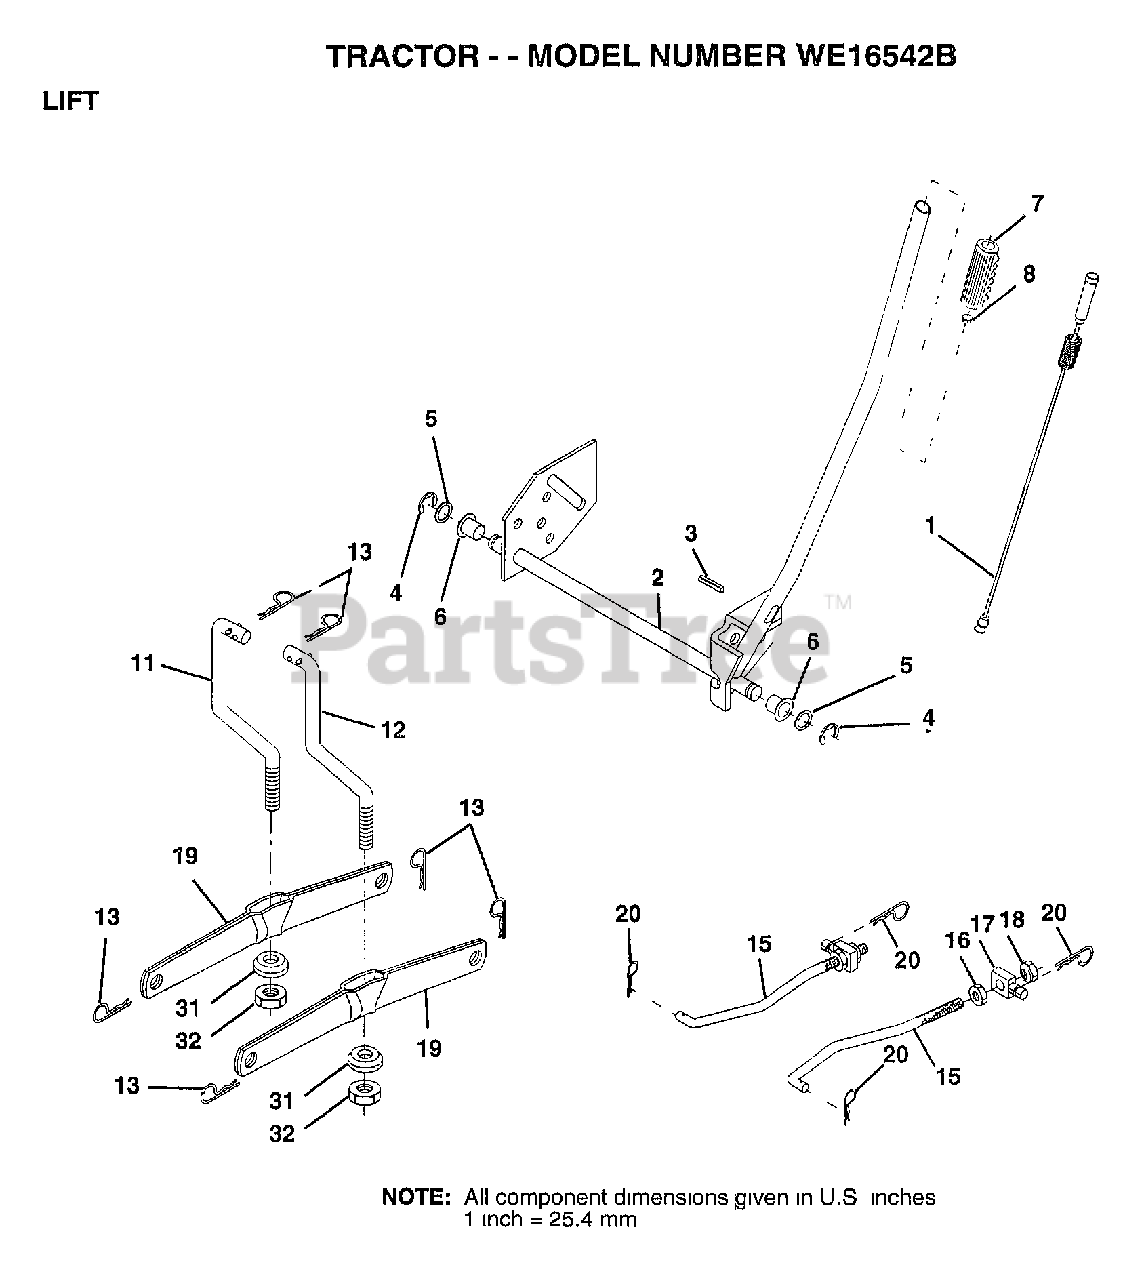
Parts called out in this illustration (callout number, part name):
1	WIRE ASM W.SPRING
2	"SHAFT ASM LIFT,RH"
3	PIN-GROOVE LT
5	WASHER
6	NYLON BEARING
7	GRIP
15	LINK.FRONT
16	NUT
17	TRUNION
18	NUT.LK.W/WSH.1/2.
19	ARM SUSP REAR
20	RETAINER SPRING
31	BEARING PVT LH
32	NUT.CROWNLOCK.3/8
